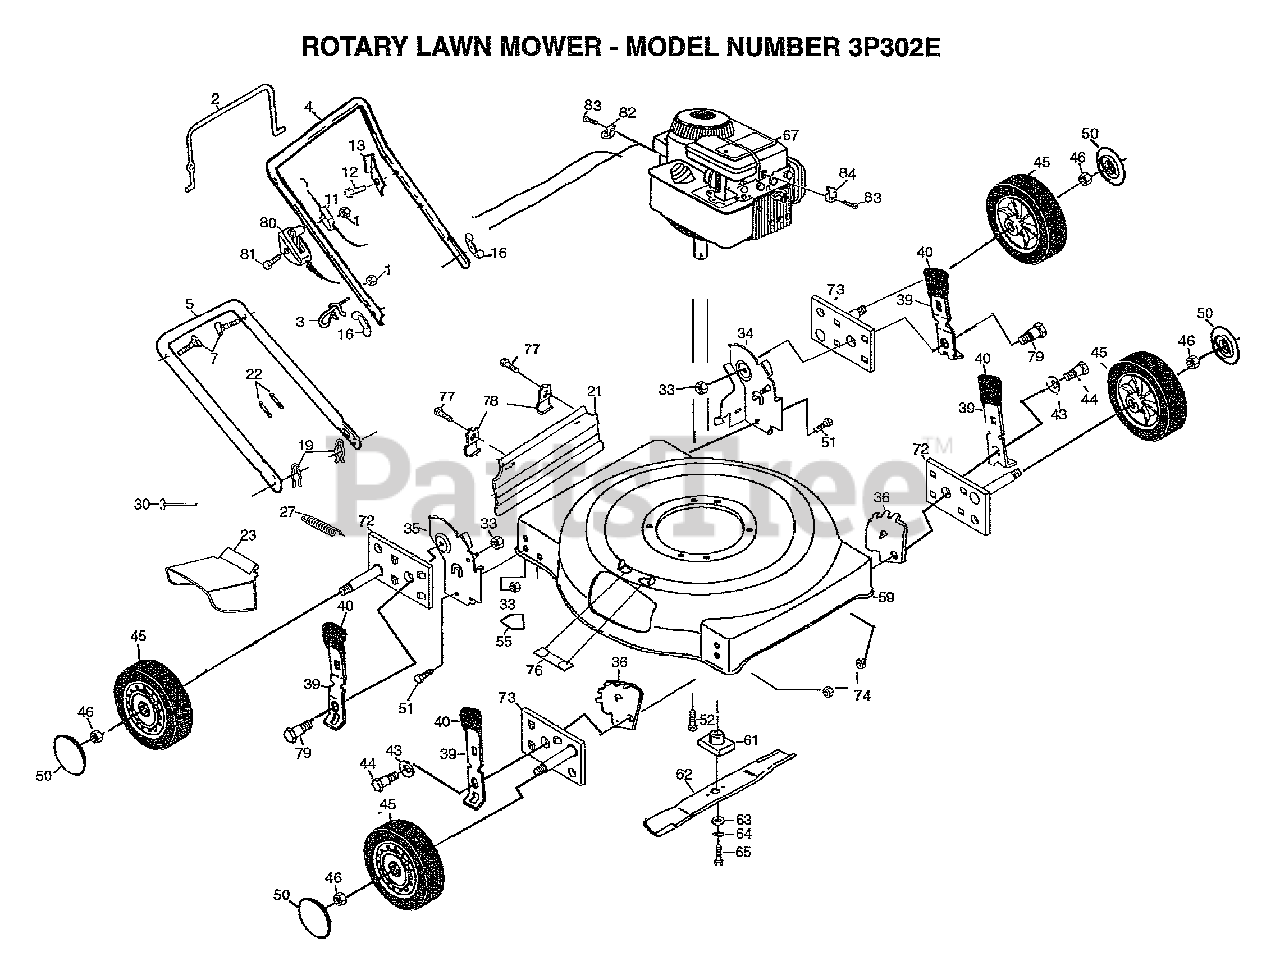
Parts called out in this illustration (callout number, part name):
2	CONTROL BAR PM
3	ROPE GUIDE
5	LOWER HANDLE
7	BOLT.HANDLE.LM
11	"CABLE,ENG ZONE CO"
12	TAPPING SCREW
13	"BRKT,UPSTOP PM"
16	"NUT,WING PM"
19	HAIRPIN COTTER
21	SKIRT.REAR.FGD.22
23	GUARD.DISCHARGE
27	HINGE.SPRING
30	HINGE.ROD.22SD
33	LOCKNUT
34	WHL BRKT SUPT LEFT
35	WHL BRKT SUPT RIGHT
36	WHEEL.BRKT.ADJ.
39	SLECTOR SPRING
40	KNOB PM
43	WASHER.BELLEVELLE
44	SHOULDER BOLT
45	WHEEL.ASM
46	HEX FLANGE LOCKNT
50	HUB CAP
51	SCREW 1/4X20
52	BOLT.ENG.3/8-16
55	DECAL HYT
59	LAWN MOWER HOUSING
61	ADAPTOR.BLADE.LM
62	"BLADE.MULCH.22"""
63	"WASHER,HARDEN"
64	LOCKWASHER
65	SCREW
72	ARM.ASM.AXLE.RR/LF
74	LOCKNUT
76	CLIP.CLOSECUT.22SD
77	TAPPING SCREW
78	"BRKT,DEFL PM"
79	SHOULDER BOLT
80	CONTROL THROTTLE
81	PAN HEAD SCREW
82	CABLE CLAMP
83	SCREW PM
84	GUIDE CLIP PM
